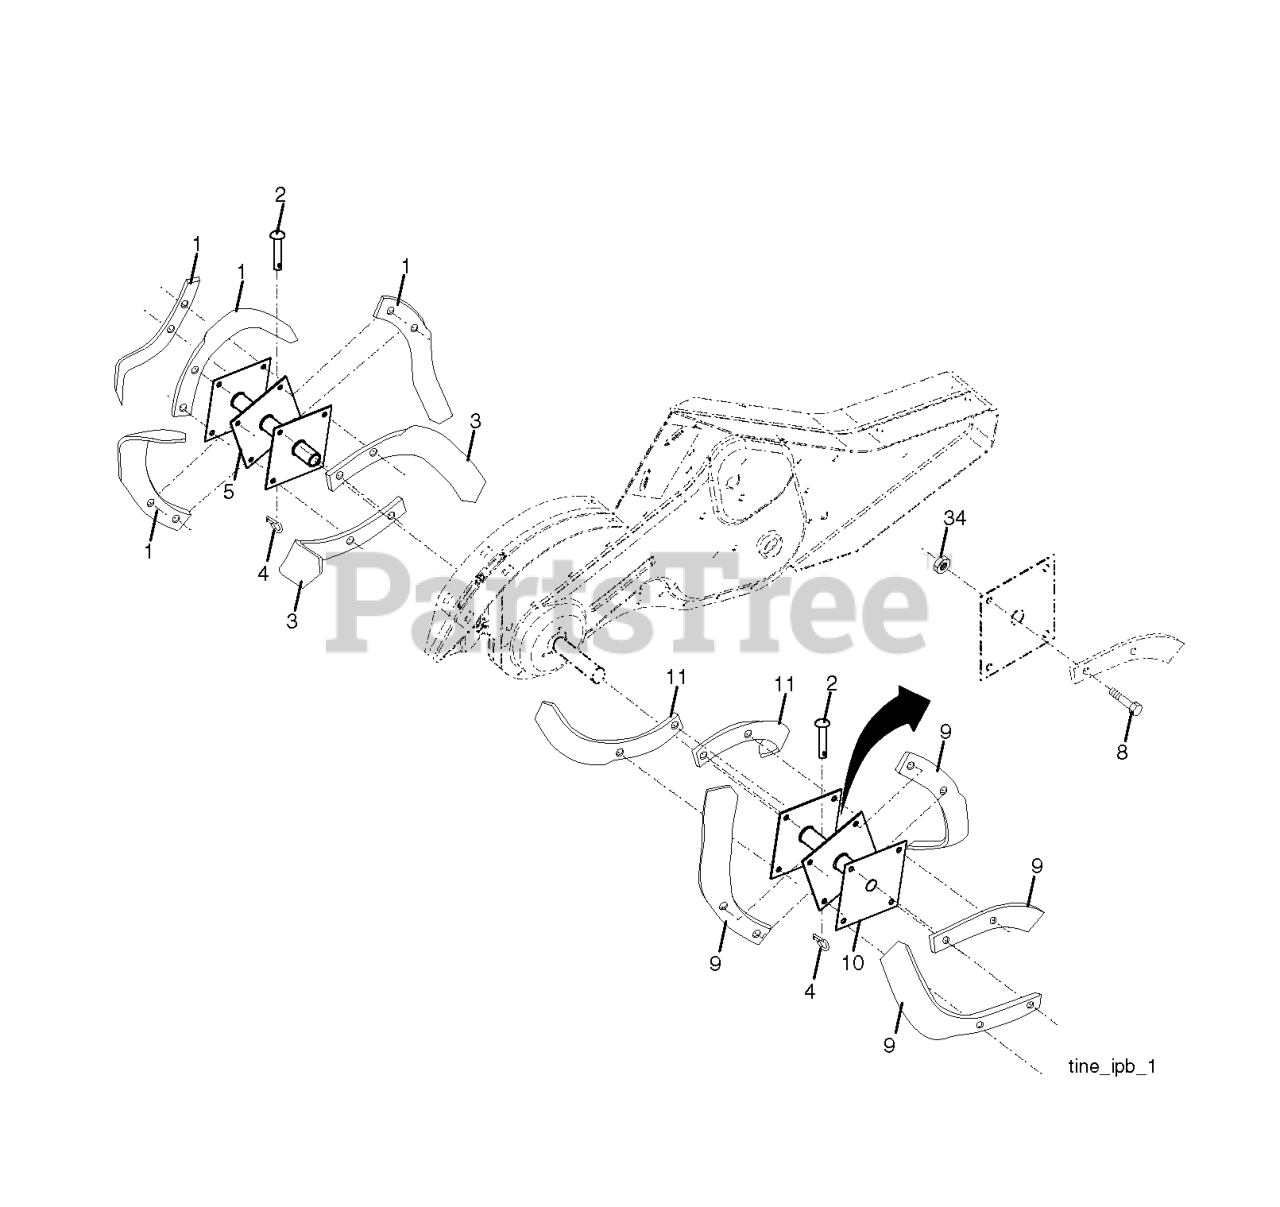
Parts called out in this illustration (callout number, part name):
1	TINE TI
2	PIN RETAINING SCREW
3	TINE.LH.12"(72L)
4	SPRING RETAINER
5	HUB.&.PLATE.ASM.LH
8	BOLT.HEX.001X20.37-24X1.ZINC
9	TINE TI
10	HUB & PLATE ASM RH
11	TINE.RH.12"(72R)
34	NUT CROWNLOCK 3/8-24
